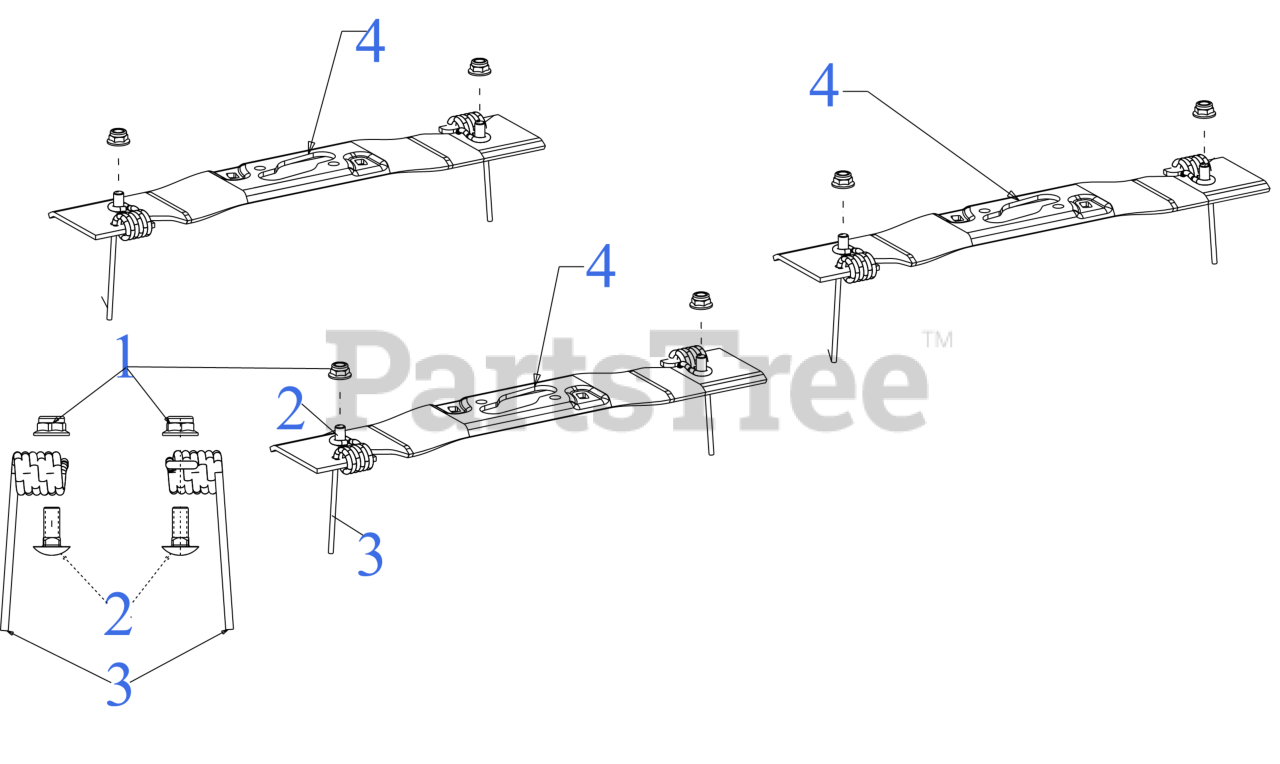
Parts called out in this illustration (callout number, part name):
1	CARRIAGE BOLT 5/16-18 x .75
2	FLANGE LOCK NUT 5/16-18
3	TORSION SPRING .529ID
4	15.82" DETHATCHING BLADE
